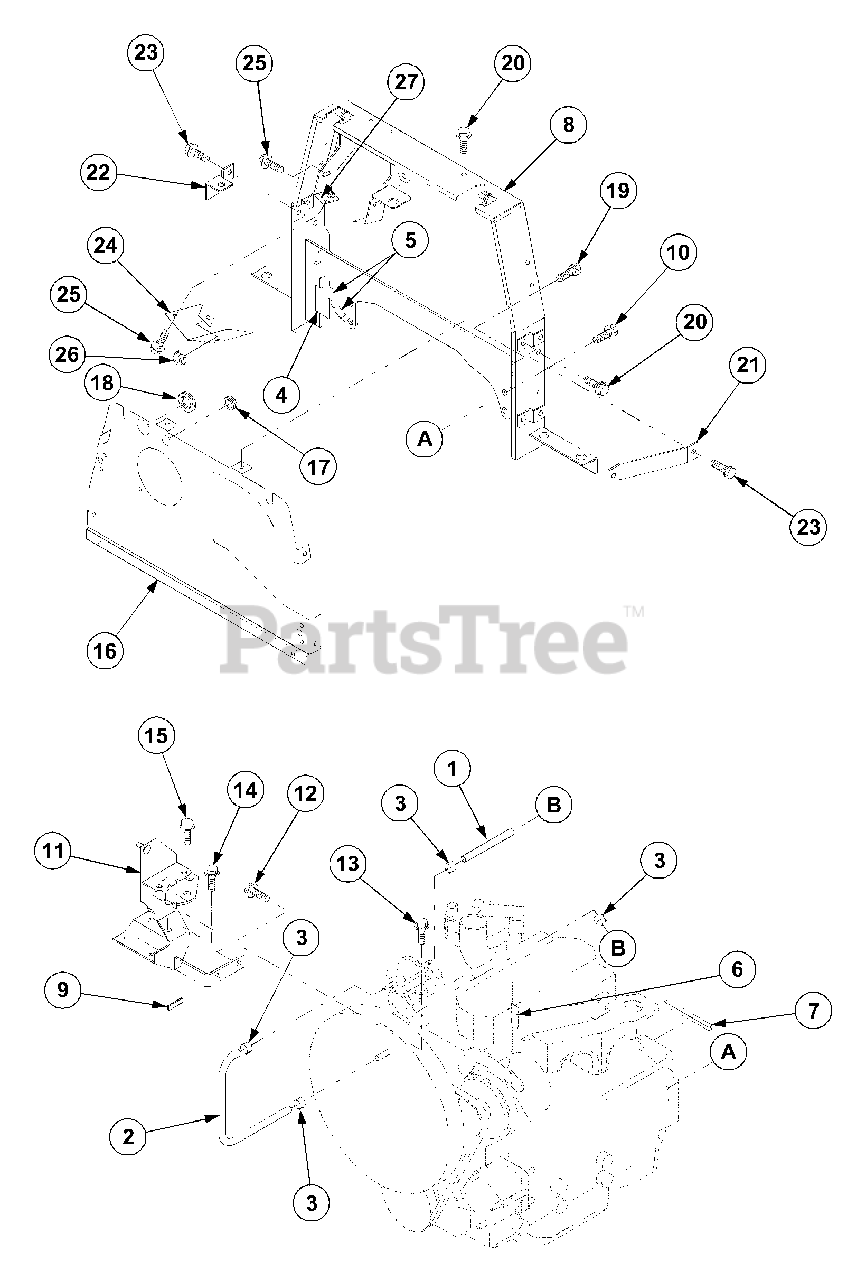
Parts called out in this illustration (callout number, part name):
10	Bolt,w/Washer
12	Bolt,w/Washer
13	Bolt,w/Washer
14	Bolt,w/Washer
15	Bolt,w/Washer
19	Bolt,w/Washer
20	Bolt,w/Washer
25	Bolt,w/Washer
